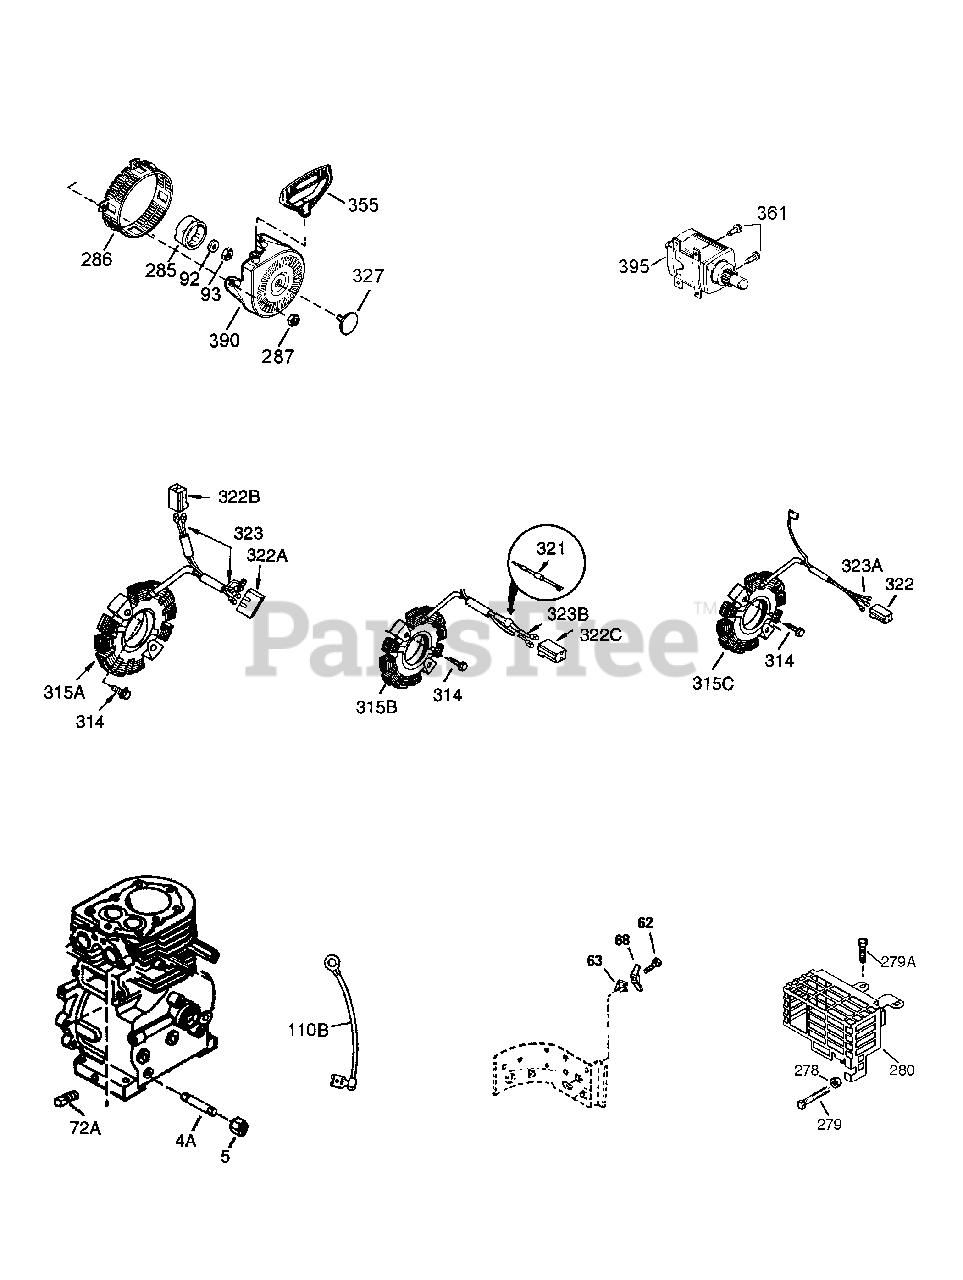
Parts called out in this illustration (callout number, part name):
5	Extension Cap
14	Flat Washer
62	Screw, 8-32 x 3/8"
92	Lock Washer
93	Flywheel Nut
130C	Screw, 5/16-18 x 1-25/32"
130C	Screw, 5/16-18 x 39/64"
285	Starter Cup
314	Screw, 1/4-20 x 3/4"
323	Terminal
329A	Screw, 10-32 x 23/64"
343	Key Switch Bracket (Incl. 343A)
355	Starter Handle (Mitten Grip) also ava ilable in Packaged Part #740053B
390	Rewind Starter NOTE: This engine cou ld have been built with 590733 starte r.
999	Winter Maintenance Kit incl. 5W30 Oil , Spark Plug, Key, & Ultra-Fresh
999	Winter Maintenance Kit (incl. 0W30 Sy nthetic Oil, Spark Plug, Key, & Ultra -Fresh)
